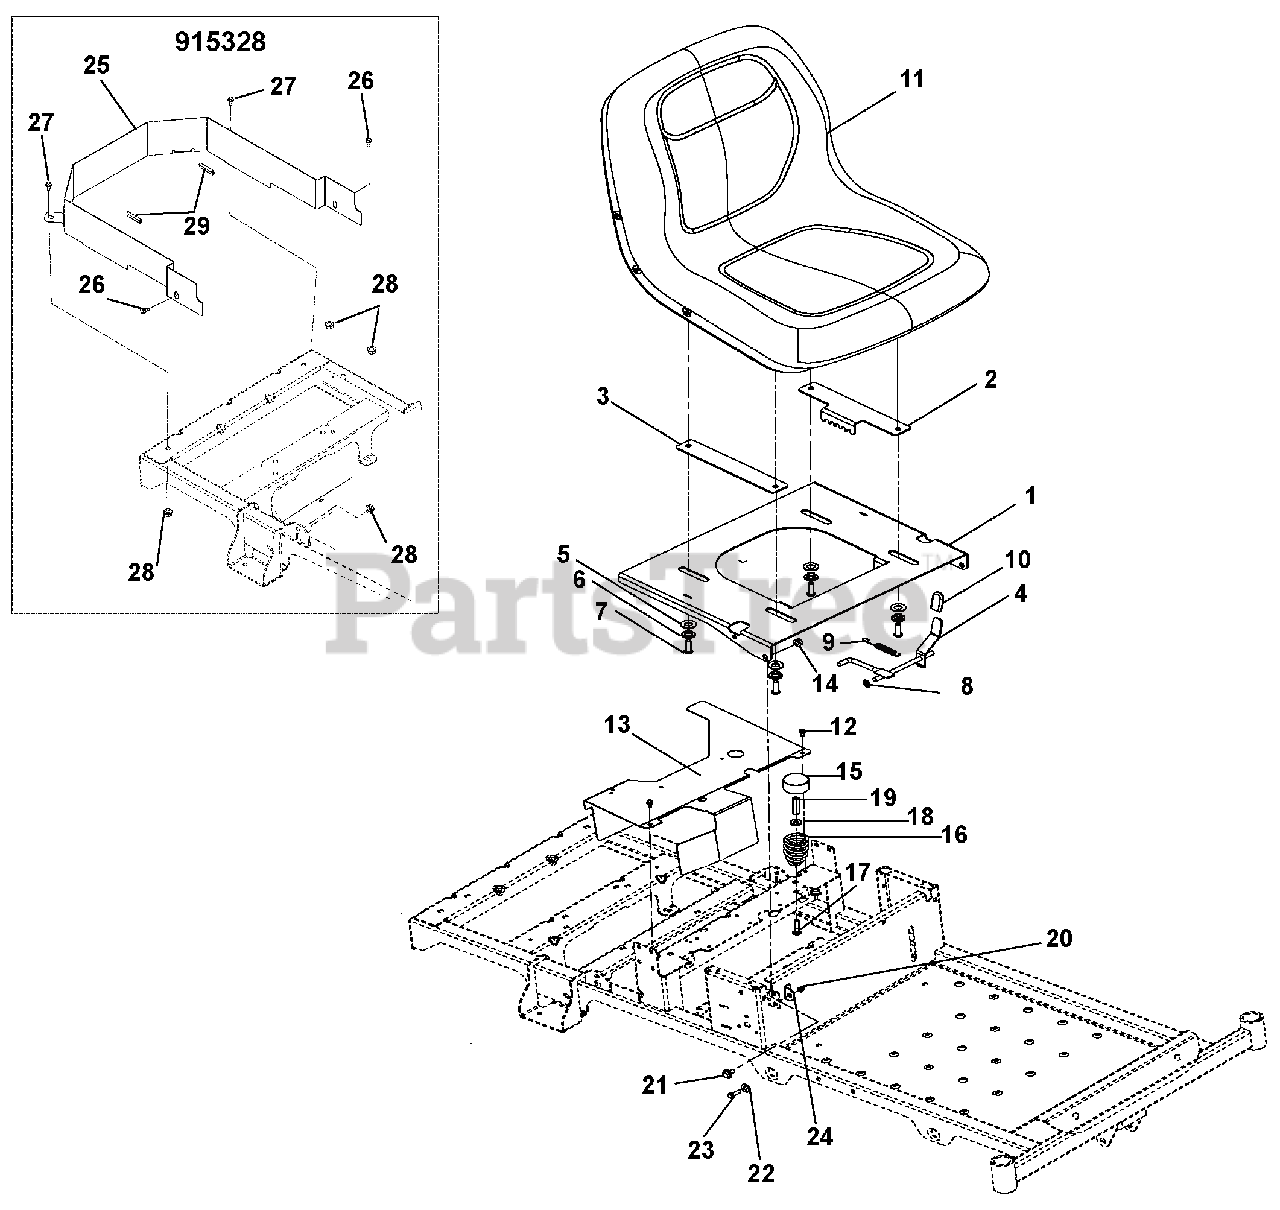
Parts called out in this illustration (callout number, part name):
1	Plate, Adjustable Seat
2	Plate, Adjustable Seat Track
3	Plate Adjustable Seat Slide
4	Weldment, Adjustable Seat Latch
5	Washer, Flat Steel .505 x 1.00 x .062
6	Bushing, Flange .32 x .500 x .344 x .880
7	Screw, Socket Head, Button Head .31-18 x 1.00
8	Push Nut 5/16
9	Spring-Tension .043 x .44 x 3.31 Weldment 5.8
10	Grip, Seat Lever, Grey
11	Seat, Milsco XB180 Grey
12	Screw, Tapping .25-20 x .50 Hex Washer Head Thread
13	Cover, Zoom CE Fan
14	Nut, .38-16 Locking Top Flange
16	Spring, Seat
17	Bolt, Round Head Square Neck .31-18 x 1.50
18	Washer, Flat Steel .328 x .87 x .179
19	Nut, Coupling 5/16-18 x 1.75
20	Nut, 5/16-18 Flange Nyloc
21	Bolt, Shoulder .375-16 x .135
22	Bushing, Flange .325 x .499 x .26 x .88
23	Bolt, Hex .31-18 x 1.00
24	Bracket, Seat Stop
25	Shield, ZT CE Reach-In
26	Bolt, Hex .38-16 x .75 Grade 5 YWCZ
27	Bolt, Hex .38-16 x 1.00 Grade 5 YWZC
28	Nut, Locking Center .38-16
29	Edging, Molded
